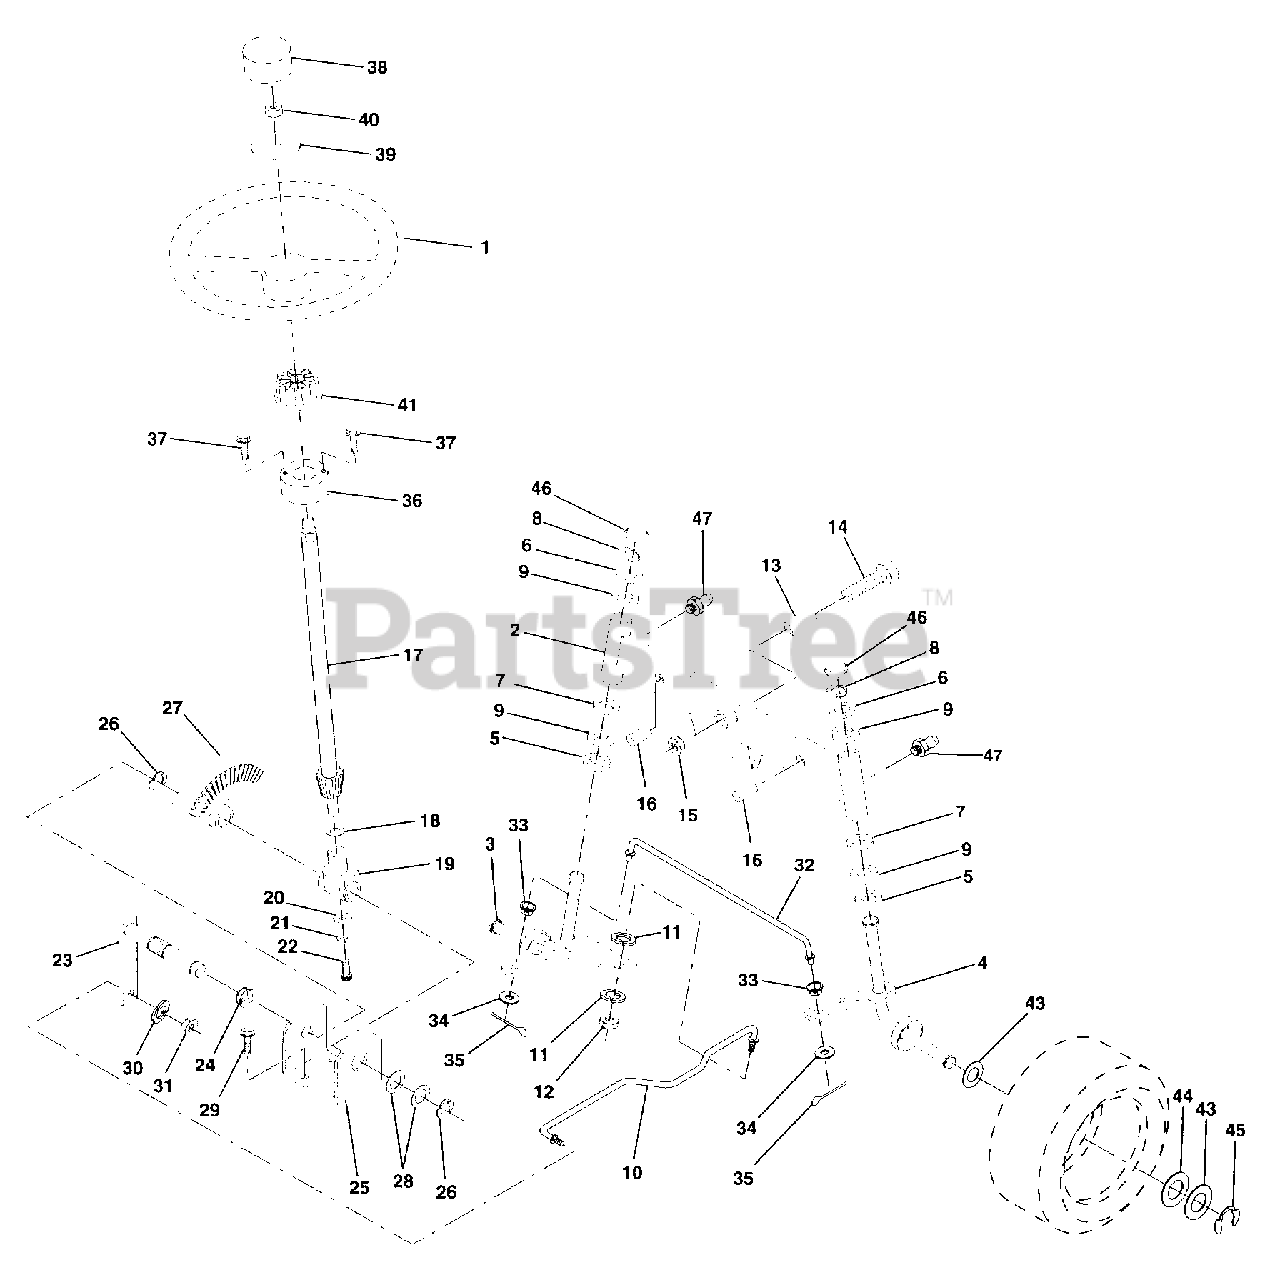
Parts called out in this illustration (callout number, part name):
2	AXLE ASM FRONT
3	SPINDLE LH
4	SPINDLE RH
5	WASHER .T
6	WASHER
7	WASHER
8	RING
9	COL. SRTG. BEAR.
11	LOCKWASHER
13	BEARING
14	BOLT HEX 5/8-11
15	"NUT-LOC,FLANGE LT"
16	AXLE PIN
17	STEERING SHAFT
18	THRUST WASHER
19	SUPPORT.SHAFT
21	LOCKWASHER
22	"SCREW,SPECIAL"
24	NYLINER T
25	"BRKT,STEERING"
26	RING
27	GEAR SECTOR
28	WASHER .T
29	SCREW
30	LOCKWASHER
32	TIE ROD
33	BUSHING.DRAGLINK
34	WASHER
35	COTTER PIN
38	"INSERT,STR WHEEL"
39	WASHER
41	ADAPTER LT
43	WASHER
44	WASHER
45	RING
46	CAP
47	ZERK M
